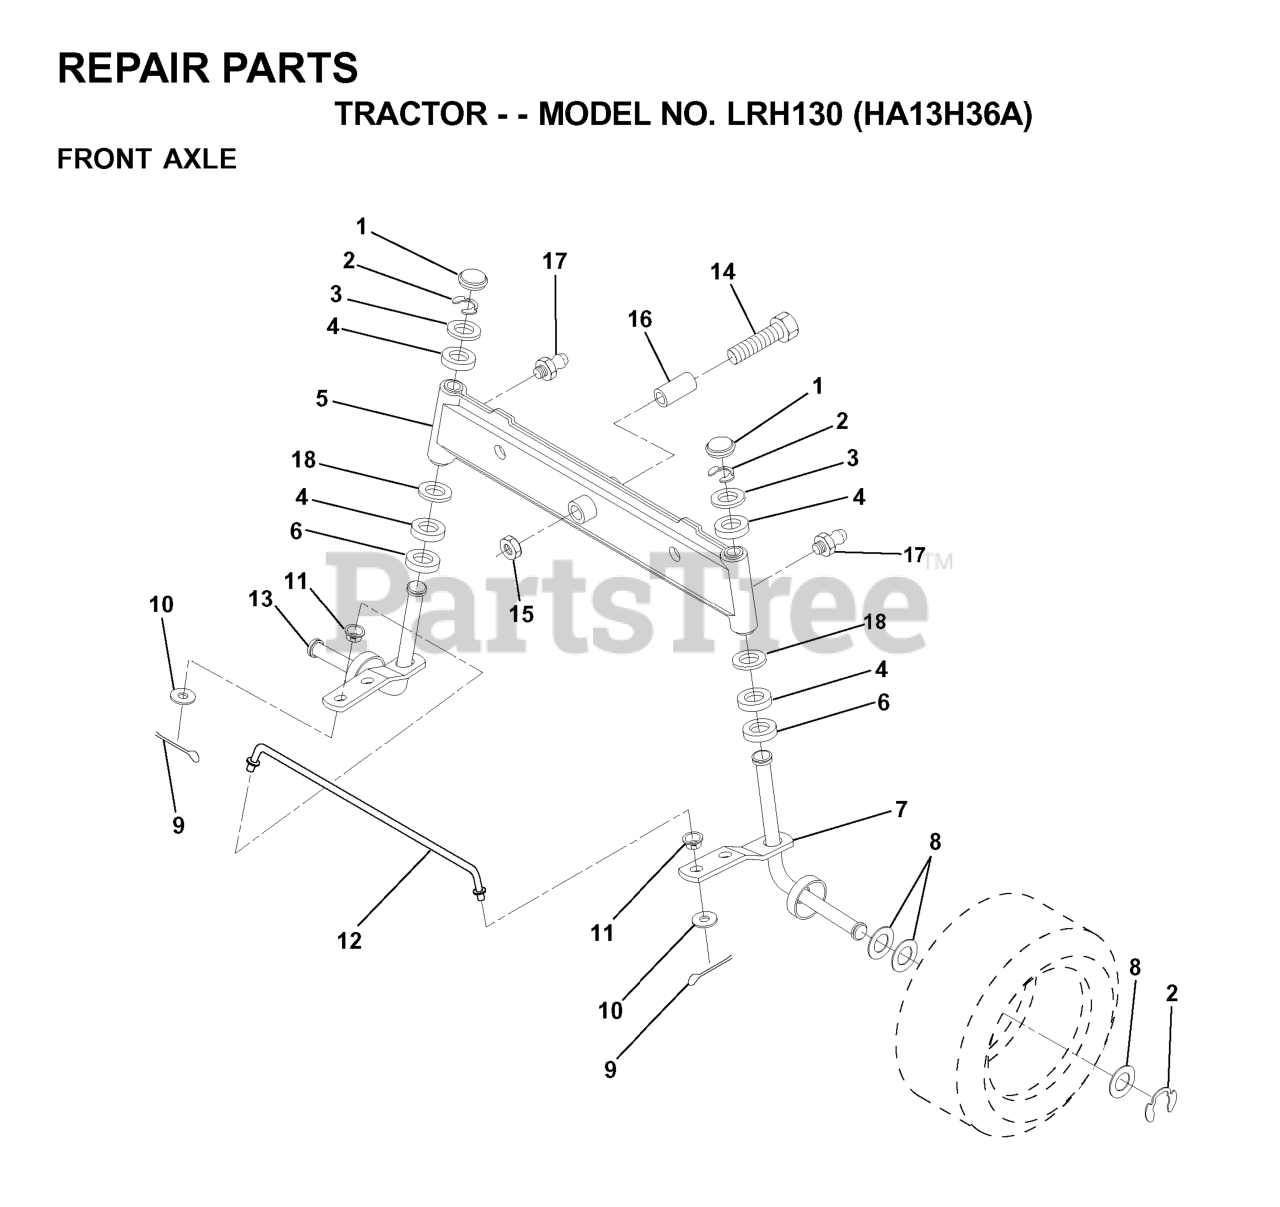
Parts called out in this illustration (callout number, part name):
1	CAP.SPINDLE.BLACK
4	BRNG T
6	THRUST WASHER
9	COTTER PIN
10	WASHER
11	BUSHING.DRAGLINK (2 2)
12	TIE ROD
13	SPINDLE.ASSEM.LH
14	Bolt, Hex Head 5/8-11 x 3-1/2
15	NUT-LOC,FLANGE LT
16	BEARING
17	ZERK M
